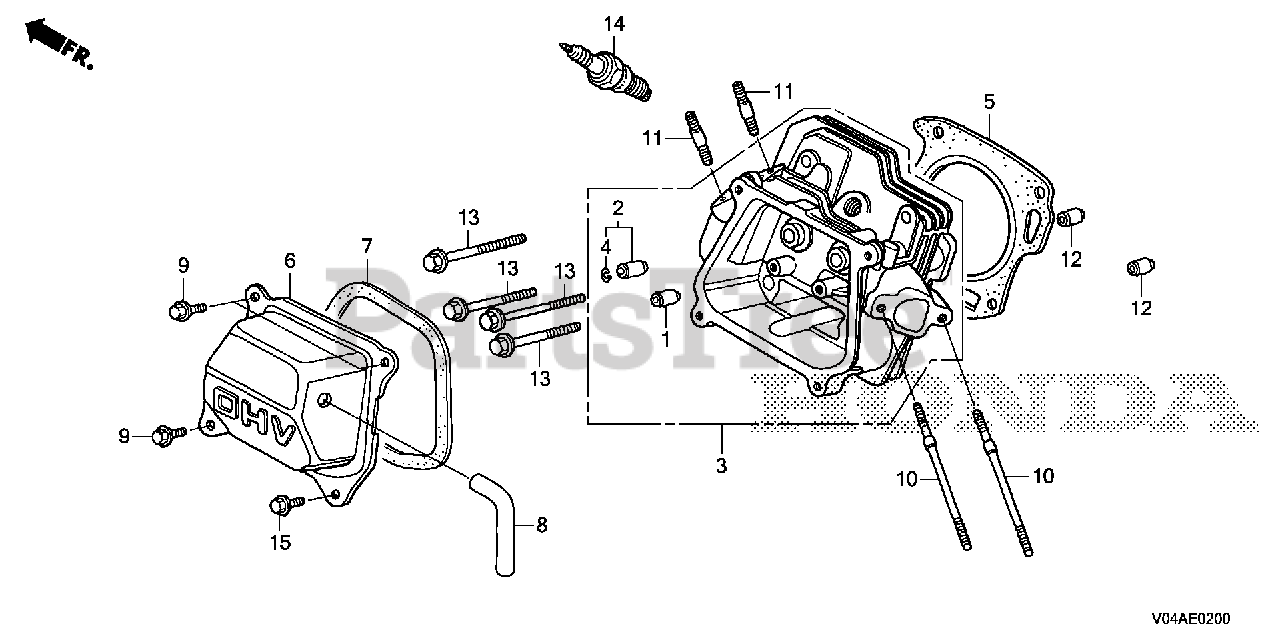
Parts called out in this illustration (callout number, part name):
1	GUIDE, VALVE (OVER SIZE)
2	GUIDE, EX. VALVE (OVER SIZE)
3	CYLINDER HEAD
4	CLIP, VALVE GUIDE
5	GASKET, CYLINDER HEAD (NIPPON LEAKLESS)
6	COVER, HEAD
7	GASKET, HEAD COVER
8	TUBE, BREATHER
9	BOLT, FLANGE (6X12) (CT200)
10	BOLT, STUD (6X112)
11	BOLT, STUD (8X32)
12	PIN, DOWEL (10X16)
13	BOLT, FLANGE (8X60)
14	SPARK PLUG (BPR5ES) (NGK)
14	SPARK PLUG (W16EPR-U) (DENSO)
15	BOLT, FLANGE (6X12) (CT200)
